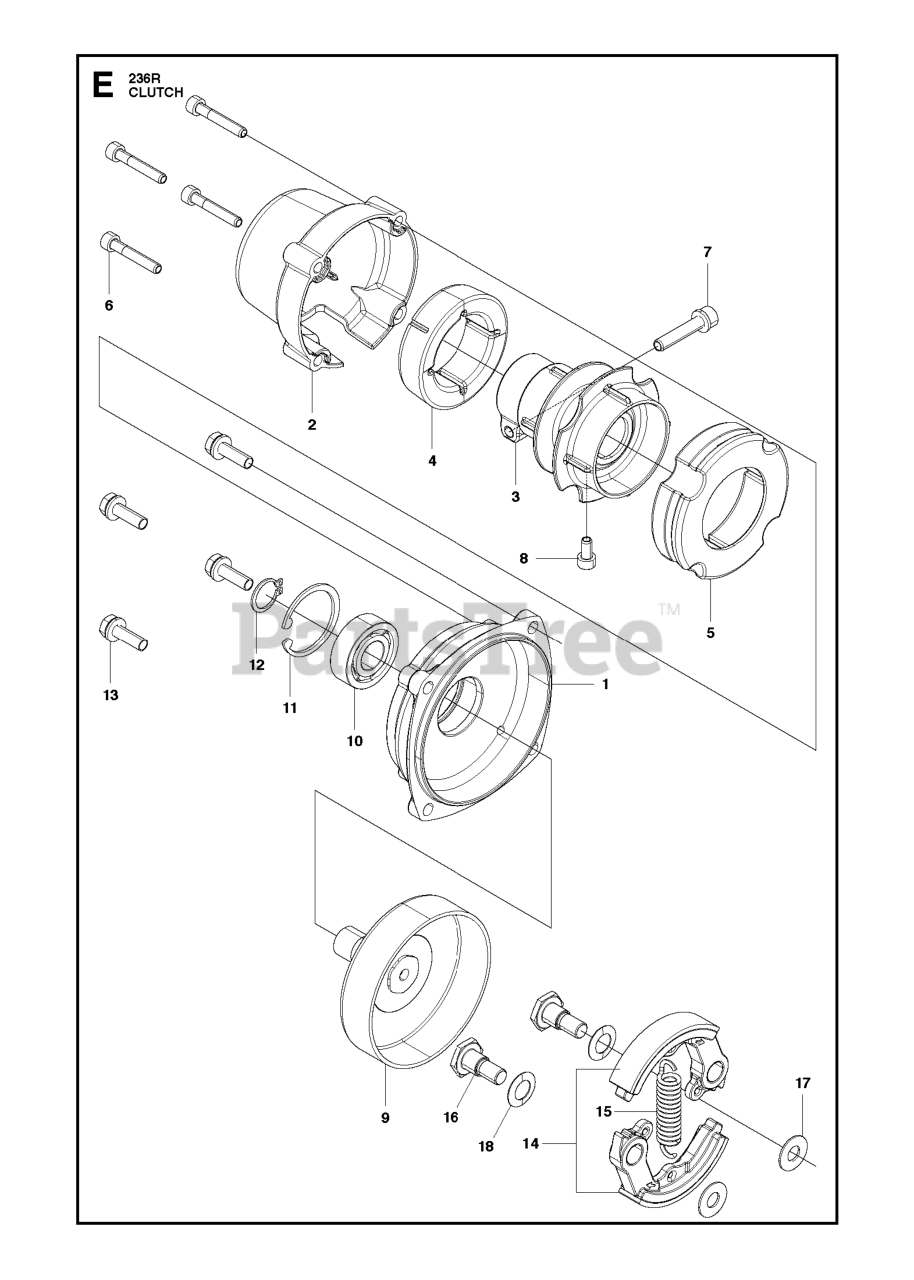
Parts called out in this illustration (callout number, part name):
7	BOLT, M6 x 30
8	BOLT M5 X L10 ALLEN BOLT
9	DRUM
10	BEARING 0600406202
11	RING
12	RING, SNAP, M15 x 1.0
117	Jets
118	Jets
121	Carburetors
125A	Carburetors
137	Gaskets
493	Brackets
617	Seals
623	Seals
975	Floats
1127	Screws
1238	Screws
